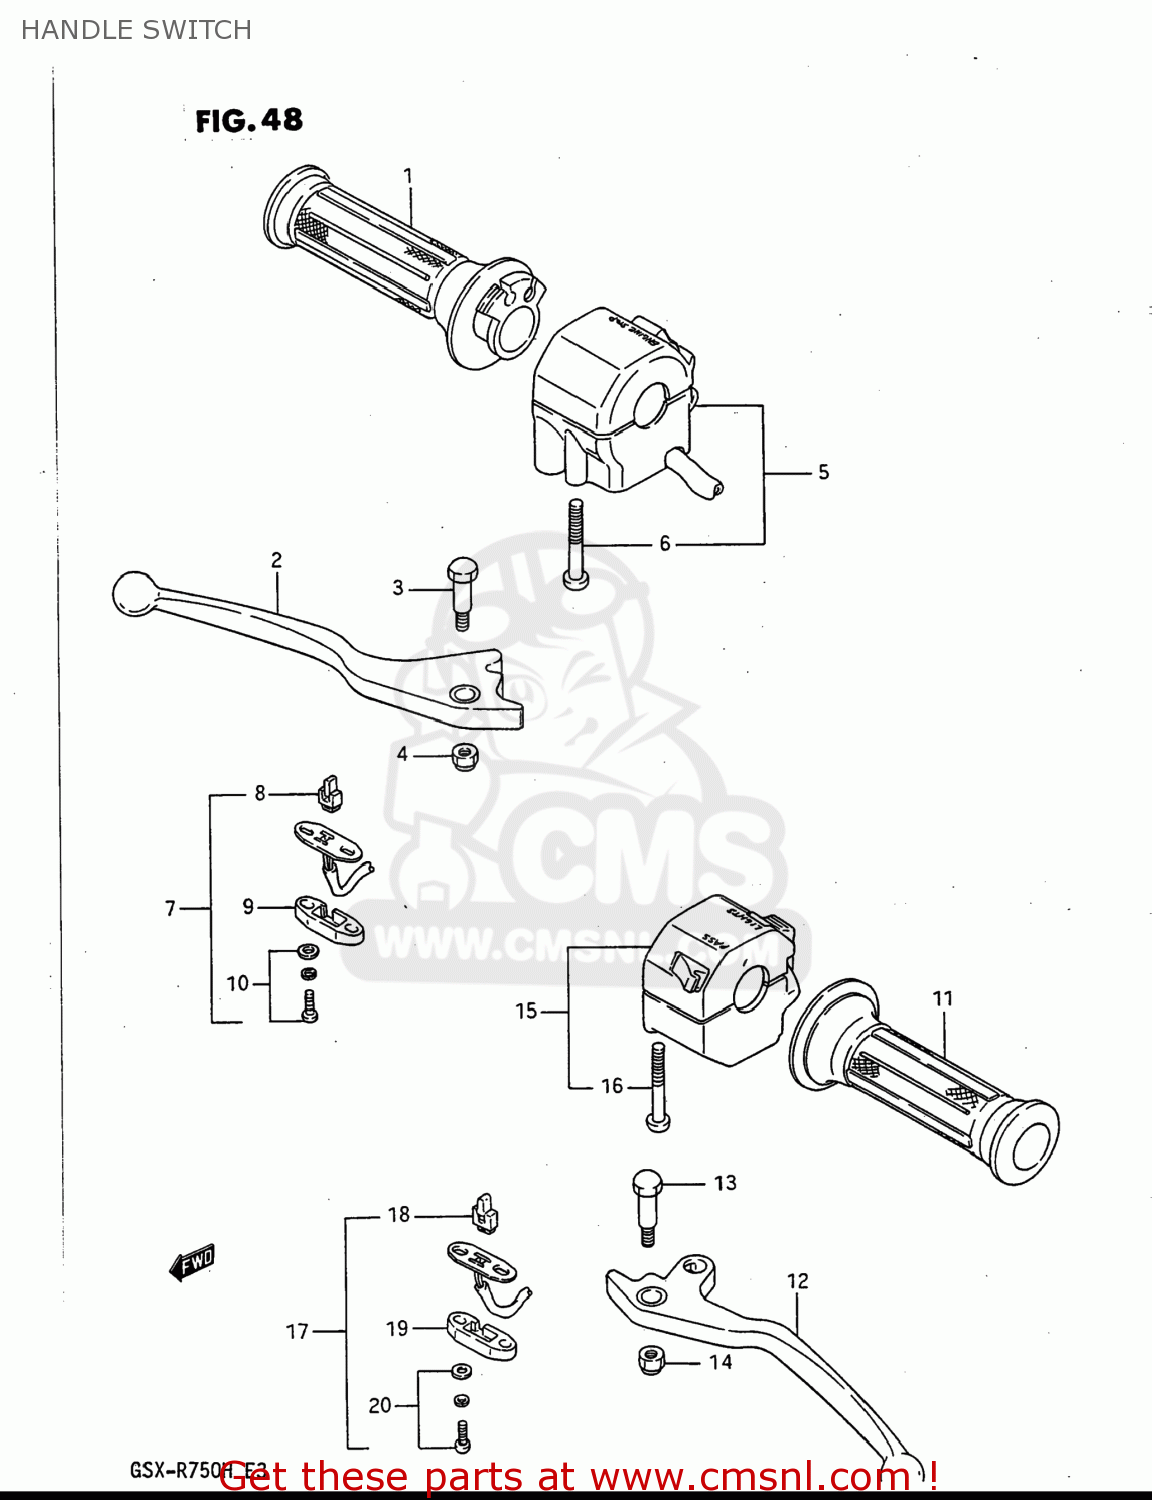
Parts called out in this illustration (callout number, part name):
1	GRIP,THROTTLE
2	LEVER,BRAKE
3	BOLT,LEVER
4	NUT
5	SWITCH ASSEMBLY,HANDLE,RIGHT
6	SCREW, 5X45
7	SWITCH ASSY,STOP
8	CONTACT,SWITCH
9	COVER,FR BK TERMINAL BASE
10	SCREW
11	GRIP,L
12	LEVER,CLUTCH (BLACK)
13	BOLT,LEVER
14	NUT
15	SWITCH ASSEMBLY,HANDLE,LEFT
16	SCREW
17	SWITCH ASSEMBLY,CLUTCH
18	CONTACT,SWITCH
19	COVER,FR BK TERMINAL BASE
20	SCREW
